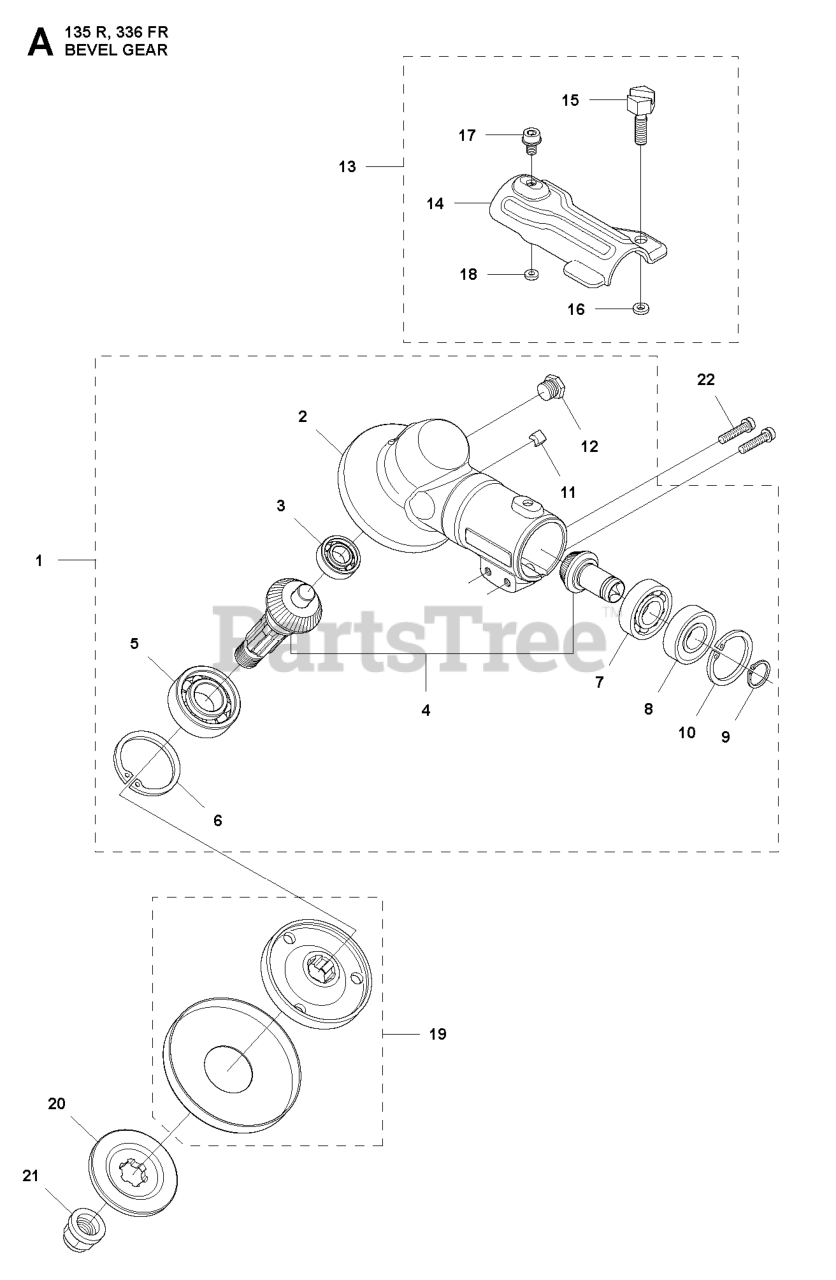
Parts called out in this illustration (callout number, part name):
1	GEAR COMPLETE
3	BALL BEARING 24X9X1/609ZR
4	SPARE PARTS KIT
5	BALL BEARING
6	RETAINING RING
7	BALL BEARING
8	BALL BEARING
9	SEEGER CLIP
10	RETAINING RING SGH 28
13	CLAMP
14	RP HOLDER
16	LOCKNUT M6
17	SCREW
18	LOCKING NUT
20	RP FLANGE
